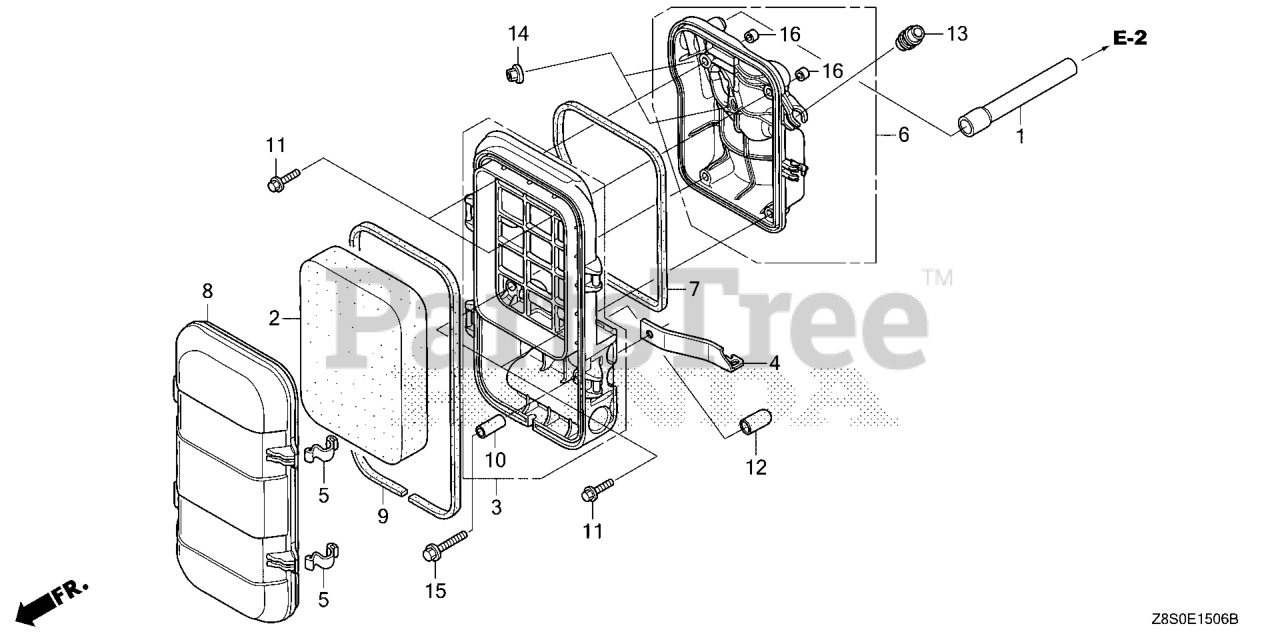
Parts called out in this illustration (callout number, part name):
1	TUBE, BREATHER
2	ELEMENT, AIR CLEANER
3	HOUSING, AIR CLEANER
4	STAY, AIR CLEANER
5	SPRING, AIR CLEANER HOUSING LID
6	BASE, AIR CLEANER
7	SEAL, AIR CLEANER HOUSING
8	COVER, AIR CLEANER
9	SEAL, AIR CLEANER COVER
10	COLLAR, AIR CLEANER
11	BOLT, FLANGE (5X18)
12	CAP, SEALING
13	RUBBER, FUEL (9X15X20)
14	NUT, FLANGE (6MM)
15	BOLT, FLANGE (6X32)
16	COLLAR, AIR CLEANER
